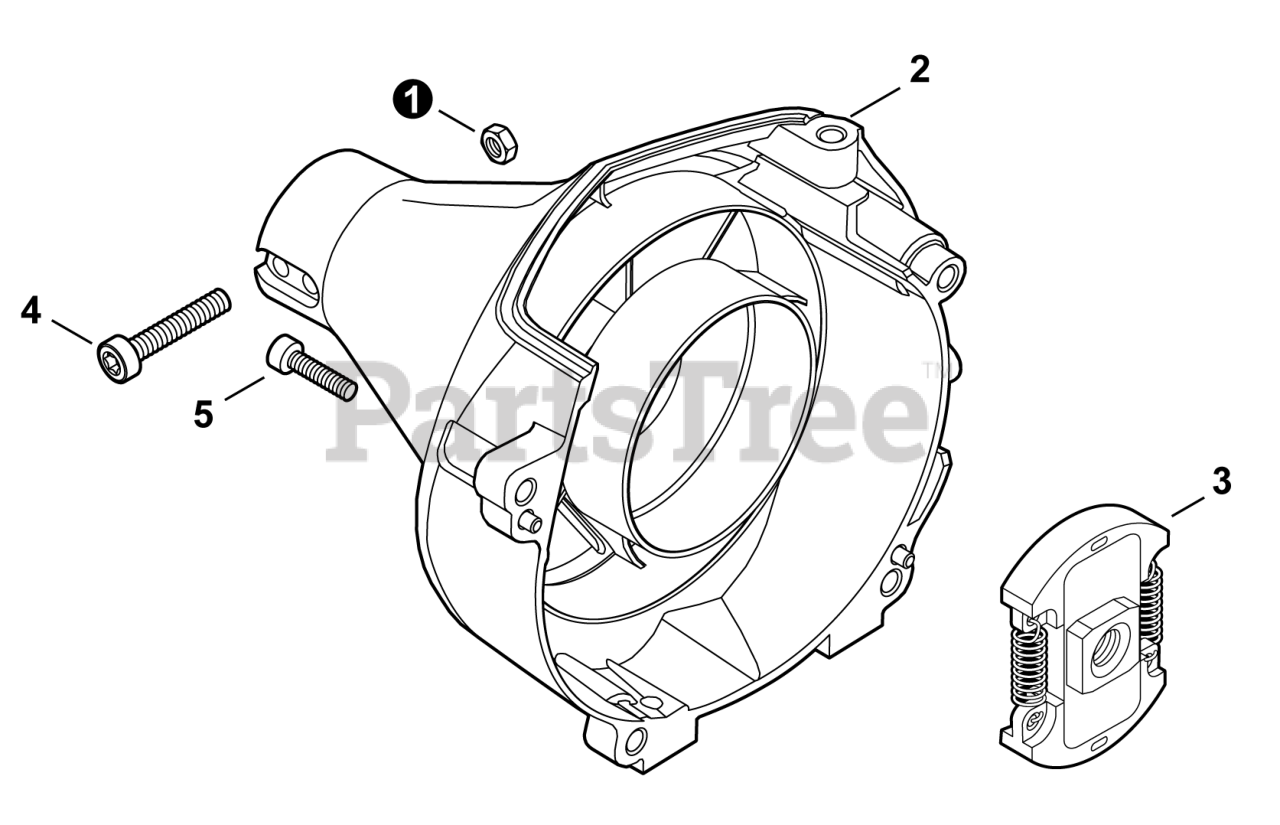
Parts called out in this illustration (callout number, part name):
2	COVER ASSY, FAN
3	CLUTCH ASSY
4	BOLT, TORX 5x25
5	BOLT, TORX 4x16
